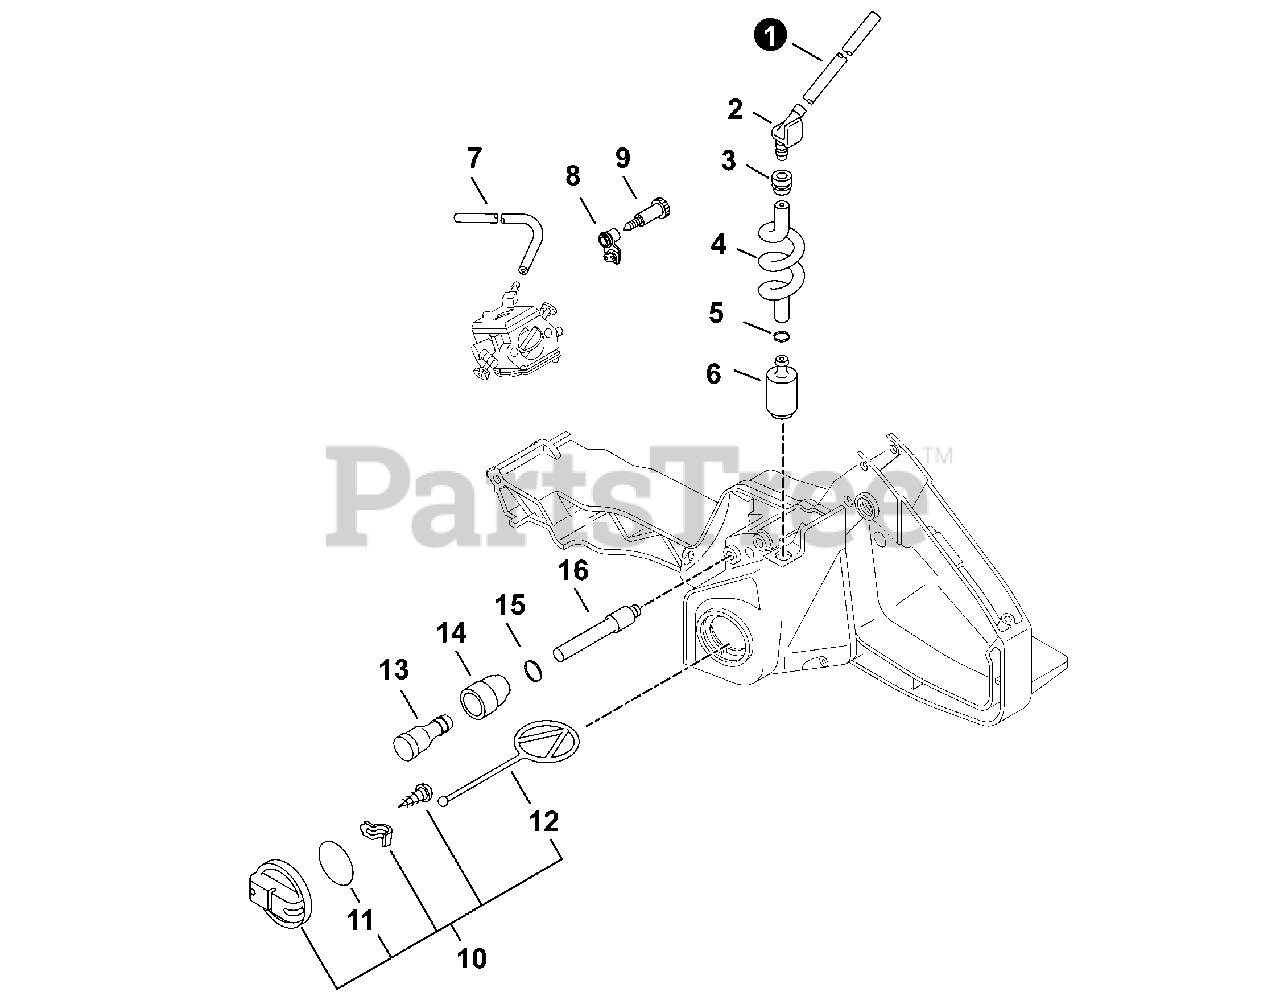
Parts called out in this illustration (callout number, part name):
1	PIPE
2	CONNECTOR, PIPE
3	GROMMET
4	PIPE, FUEL
5	CLIP Ø6.5 MM
6	FILTER, FUEL
7	PIPE, IMPULSE 3×6(8)×160
8	GROMMET, NEEDLE
9	SCREW, IDLE ADJUST
10	CAP ASSY, FUEL
11	O-RING 29
12	CONNECTOR, CAP L= 60 MM
13	VENT ASSY
14	HOLDER, VENT
15	CLIP 5.5
16	PIPE 3×5×55
